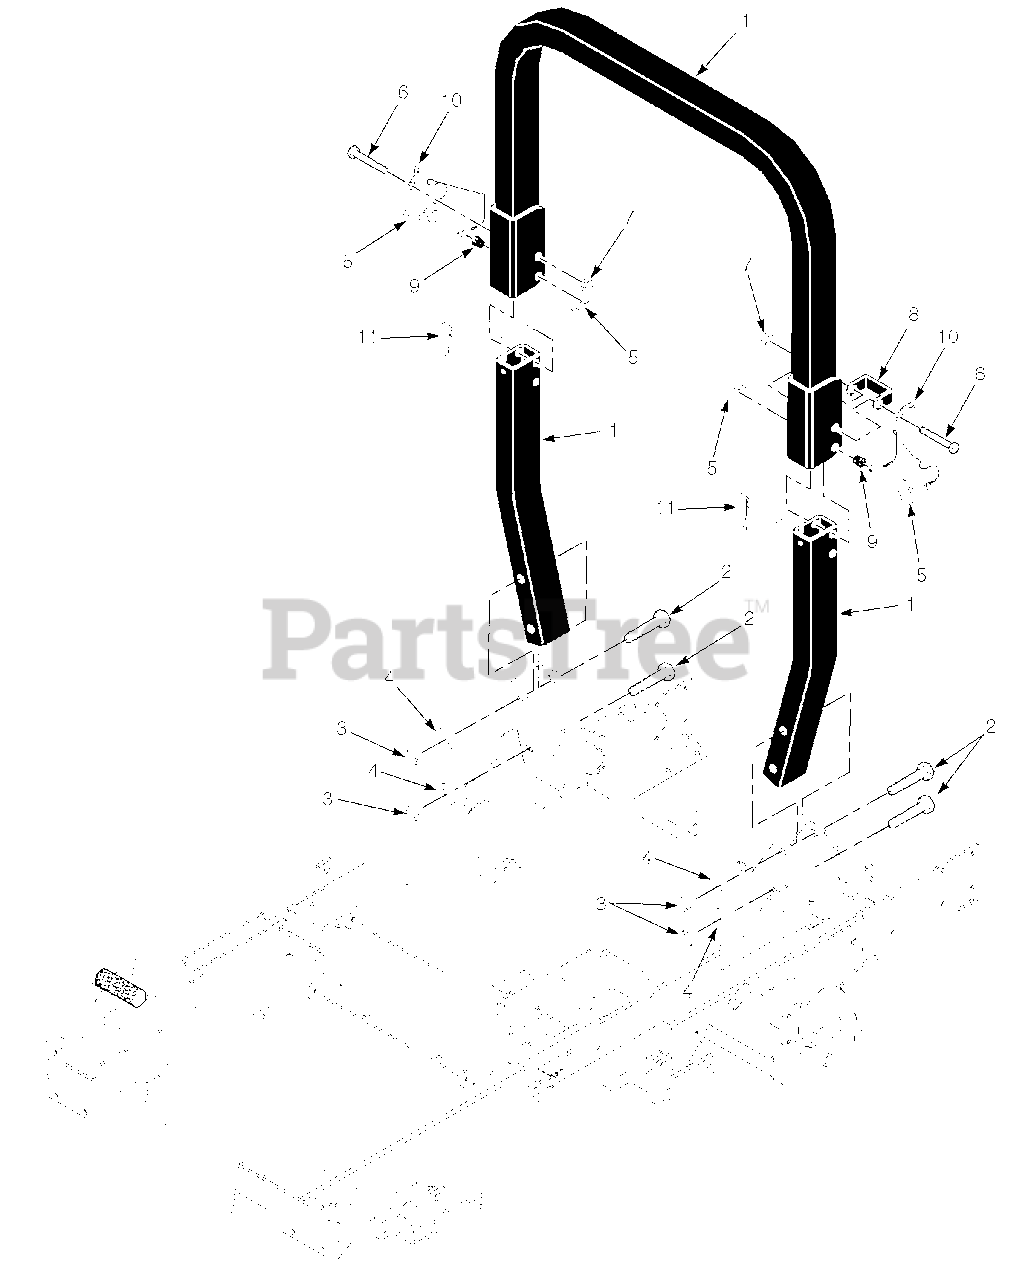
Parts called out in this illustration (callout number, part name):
1	STT, ROPS
2	Bolt, Hex Head 1/2-13 x 4"
3	Nut, Center Lock 1/2-13
4	Flatwasher, 1/2-.562 x 1.375 x .109
5	Pin Assembly
6	Bolt, Hex Head 1/2-13 x 3-3/4"
7	Nut, Center Lock 1/2-13
8	Stop Bracket, ROPS
9	Spring, ROPS
10	Clip, ROPS
11	Spring Clip, ROPS
